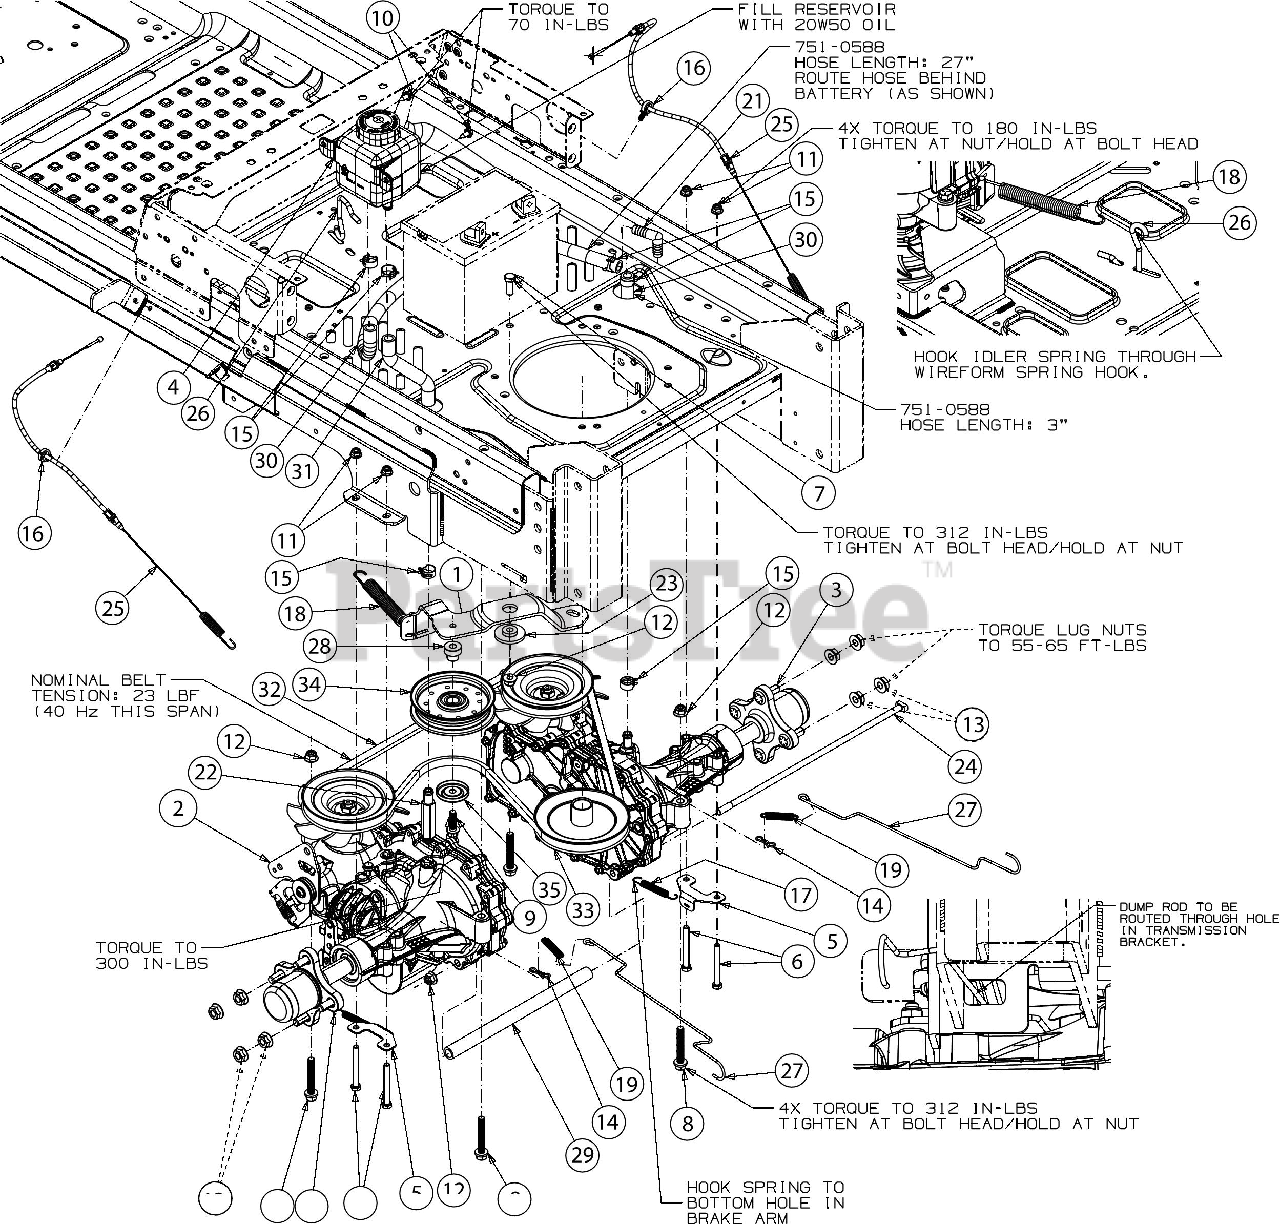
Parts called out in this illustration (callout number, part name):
1	IDLER BRACKET ASSEMBLY
2	TRANSMISSION ASSEMBLY (LH)
3	TRANSMISSION ASSEMBLY (RH)
4	HYDRAULIC TANK
6	HEX SCREW 5/16-18 x 2.75
7	SCREW 3/8-16 x 1 GR5
8	SCREW 3/8-16 x 2.25 GR5
9	SCREW 3/8-16 X1.250
10	SCREW 1/4-20X.625
11	FLANGE LOCK NUT 5/16-18
13	HEX FLANGE NUT 7/16-14
14	BOW TIE COTTER PIN 1/4-5/16
15	FUEL HOSE CLAMP
16	CABLE RETAINER CLIP
17	EXTENSION SPRING .38 OD x 3.25 LG
18	EXTENTION SRING .75 DIA. x 6.85
19	EXTENSION SPRING .380 ODX 2.000 LG
21	90 DEGREE NYLON FITTING
22	EXTENSION FITTING 9/16-18
23	SHOULDER SPACER
24	SUPPORT TUBE ROD
25	PARK BRAKE CABLE
26	IDLER SPRING HOOK
28	SHOULDER SPACER
29	TRANSMISSION SPACER .75OD x 11.31
30	FUEL LINE 1/2" ID
31	TRANSMISSION EXPANSION HOSE
32	TRANSMISSION DRIVE BELT A x 67
33	ELECTRIC PTO PULLEY
34	IDLER PULLEY 4.25 DIA
35	IDLER PULLEY CAP
